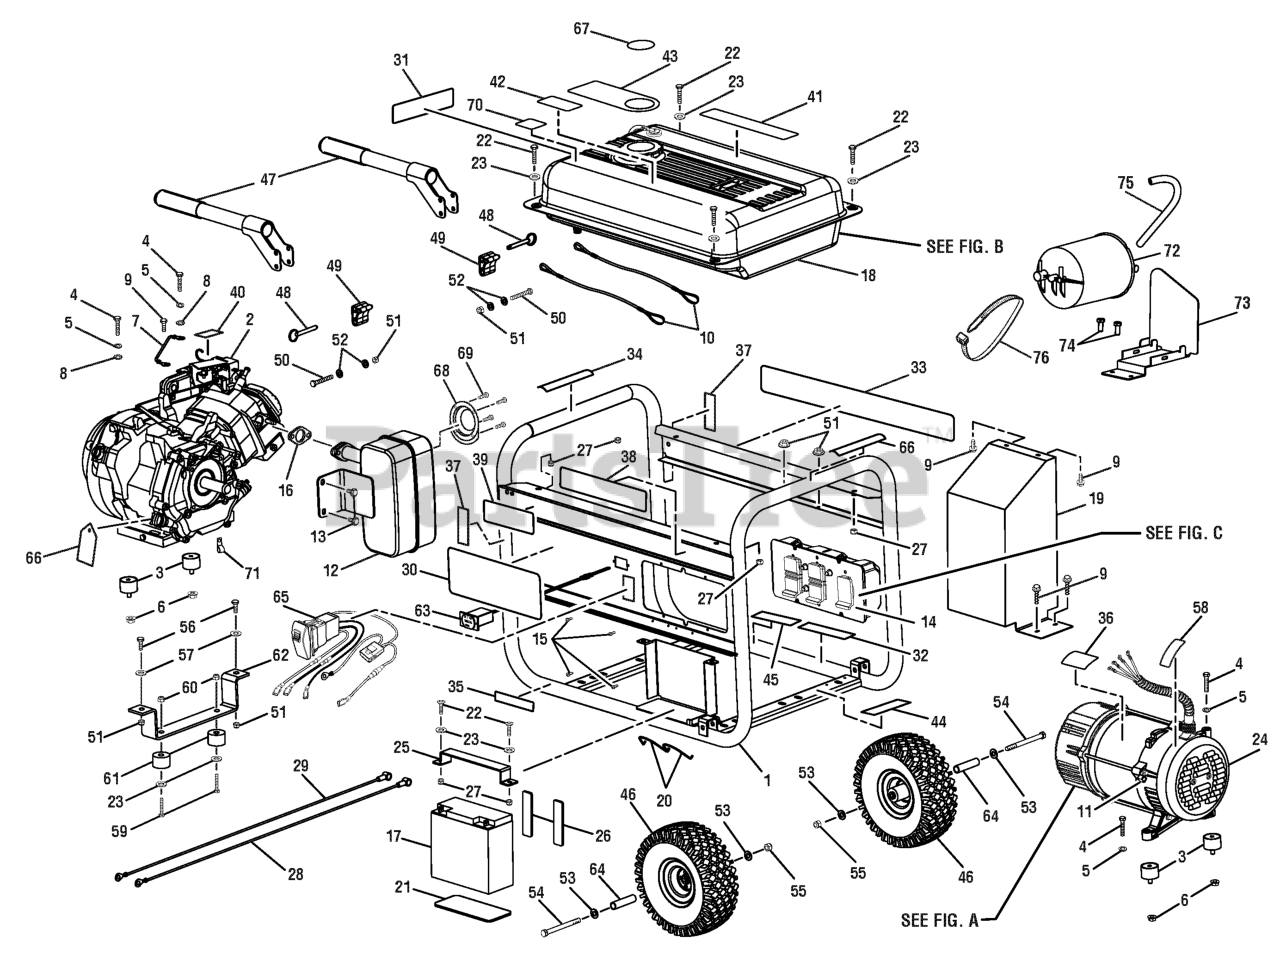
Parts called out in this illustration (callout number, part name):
1	CARRIER ASSEMBLY
2	Engine (Honda GX390)(Parts are available at your local Honda dealer)
3	ISOLATOR
4	BOLT (5/16-18 X 1-1/2 IN HXHD)
5	LOCK WASHER (5/16 IN.)
6	FLANGE NUT (5/16-18 HEX HD.)
7	GROUND WIRE ASSEMBLY
8	STAR WASHER (5/16 IN.)
9	BOLT (5/16-18 X 3/4 IN HEX HD)
10	LANYARD (3/16 IN.)
11	GROUND LUG
12	MUFFLER
13	BOLT (5/16-24 X 5/8 IN.)
14	CONTROL PANEL ASSEMBLY
15	SCREW (6-20 X 3/8 IN.)
16	MUFFLER GASKET
17	BATTERY
18	FUEL TANK ASSEMBLY
19	HEAT SHIELD
20	CORD RETAINER
21	BATTERY BOX GASKET
22	BOLT (1/4-20 X 1 IN. HEX HD.)
23	WASHER (1/4 IN.)
24	GENERATOR HEAD W/AVR
25	BATTERY HOLD DOWN BRACKET ASSM
26	GASKET (BATTERY HOLD DOWN
27	LOCK NUT (1/4-20)
28	BATTERY CABLE (RED)
29	BATTERY CABLE (BLACK)
30	LOGO LABEL
31	STARTING INSTRUCTIONS LABEL
32	HOT SURFACE LABEL
33	DANGER LABEL
34	FIRE DANGER LABEL
35	ENGINE LUBRICANT LABEL
36	DATA PLATE LABEL
37	LOCKING PIN LABEL
38	HONDA LABEL
39	ELECTRIC START LABEL
40	CHOKE LABEL
41	QUICK START LABEL
42	CPSC LABEL
43	HANGTAG (ENGINE WARNING)
44	GROUND WARNING LABEL
45	COMBUSTION WARNING LABEL
46	WHEEL ASSEMBLY
47	HANDLE ASSEMBLY
48	RELEASE PIN (5/16 X 2 IN.)
49	HANDLE BRACKET SPACER
50	BOLT (5/16-18 X 2-1/4 IN HXHD)
51	LOCK NUT (5/16)
52	WASHER (5/16 IN.)
53	WASHER (3/16 IN.)
54	BOLT (3/8-16 X 4-1/4 IN HX HD)
55	NUT (3/8-16)
56	BOLT (5/16-18 X 1 IN. HEX HD.)
57	FLAT WASHER (5/16 IN.)
58	GROUND LABEL
59	BOLT (1/4-20 X 1-1/2 IN HX HD)
60	LOCK NUT (1/4-20)
61	RUBBER FOOT
62	FRONT FOOT
63	HOUR METER (120 VOLT)
64	WHEEL SPACER
65	ENGINE SWITCH
66	FIRE DISTANCE LABEL
67	FUEL STABILIZER LABEL
68	SPARK ARRESTOR
69	SCREW (8-32 X 3/8 IN.)
70	E85 LABEL
71	J-CLAMP
72	CANISTER
73	BRACKET
74	BOLT (5/16-18 X 3/4 IN.)
75	PURGE HOSE
76	CABLE TIE
